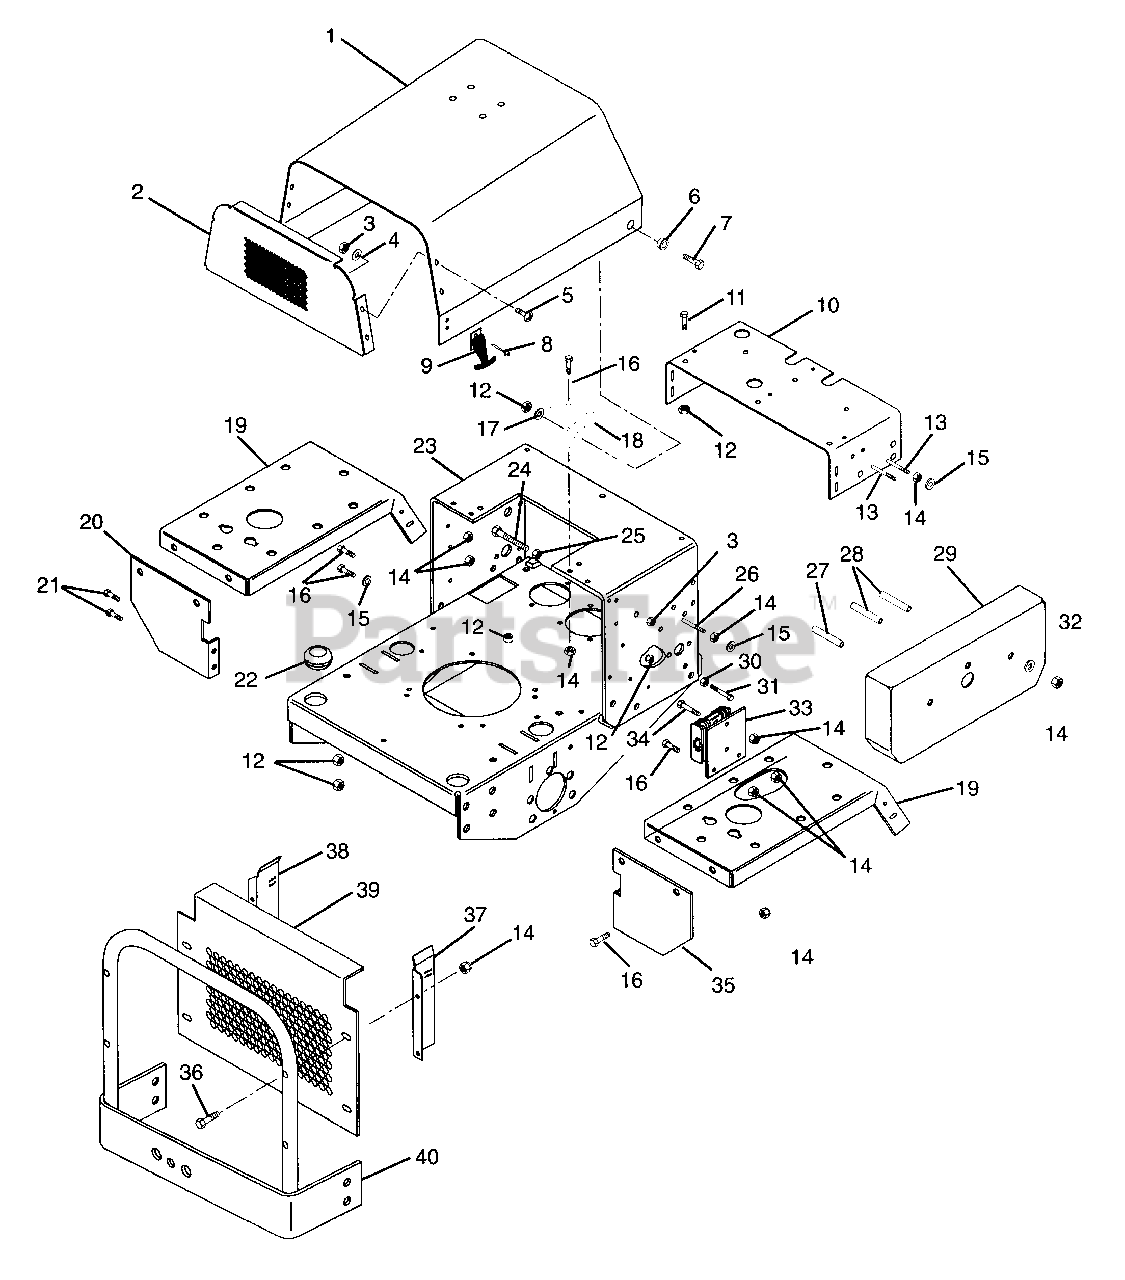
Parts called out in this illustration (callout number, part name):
1	Cover-Engine
2	Grille-Hood
3	Nut-Locking-Center .250-20
3	Nut-Locking-Nylon .250-20 Grade 2
4	Washer-Flat-Steel .281 x .620 x .065
5	Screw-Machine .25-20
6	Bushing-Flange .406 x .88 x .270 x .140
7	Bolt-Hex .38-16 x 1.00 Grade 5
8	Rivet .125 x .245
9	Latch-Flexible
10	Panel-Silkscreen
11	Bolt-Hex .38-16 x 1.00 Grade 5
12	Nut-Locking-Center .375-16
13	Bolt-Hex .31-18 x 4.00 Grade 5
14	Nut-Locking-Center .312-18
14	Nut-Locking-Nylon .312-18 Grade 2
15	Washer-Flat-Steel .344 x .688 x .065
16	Bolt-Hex .31-18 x .75 Grade 5
17	Washer-Flat-Steel .406 x .812 x .065
18	Bracket-Hood Mounting Right-Hand
18	Bracket-Hood Mounting Left-Hand
19	Fender PM200
20	Support-Fender Left-Hand
21	Bolt-Hex .38-16 x 1.25 Grade 5
23	Weldment-Frame PM200
24	Bolt-Hex .25-20 x 3.00
25	Nut .25-20
26	Bolt-Hex .312-18 x 3.75
27	Spacer-Split-Rolled
28	Spacer-Split-Rolled
29	Guard-Linkage
30	Nut-Hex .375-16
31	Bolt-Hex .38-16 x 3.00 Grade 5
32	Washer-Flat-Steel .328 x .875 x .062
33	Plate-Regulator Rectifier Mounting
34	Bolt-Hex .31-18 x 1.25 Grade 5
35	Support-Fender Right-Hand
36	Bolt-Hex .31-18 x 1.50 Grade 5
37	Bracket-Hood Latch Right-Hand
38	Bracket-Hood Latch Left-Hand
39	Bracket-Hood Support
40	Weldment-Rear Guard
